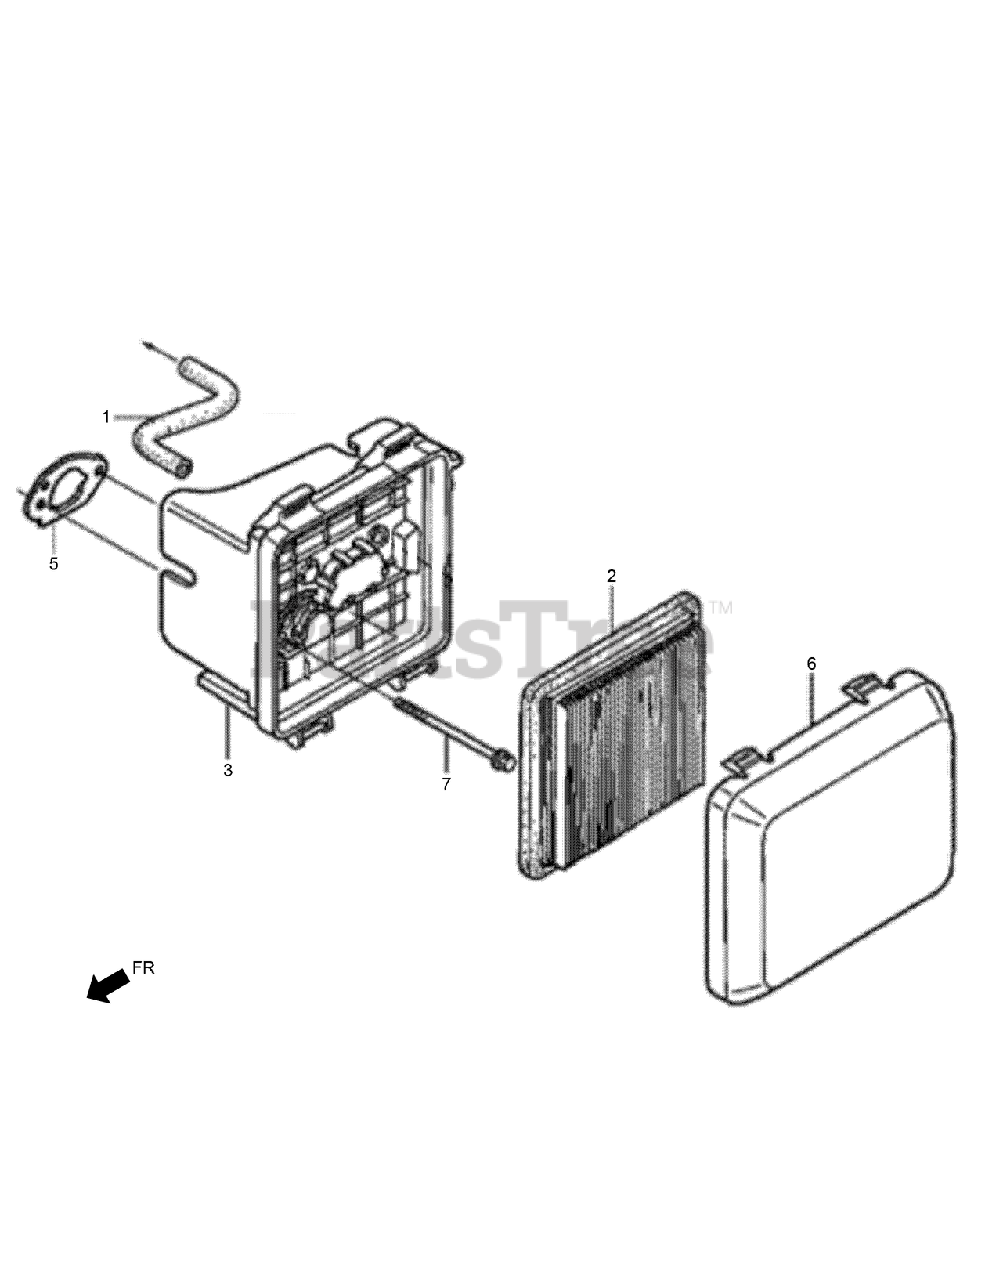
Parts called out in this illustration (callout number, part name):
1	TUBE-BREATHER
2	ELEMENT-AIR CLEANER
3	CASE ASM-AIR CLEANER
5	PACKING-AIR CLEANER
6	COVER-AIR CLEANER
7	BOLT-SPECIAL-6MM
